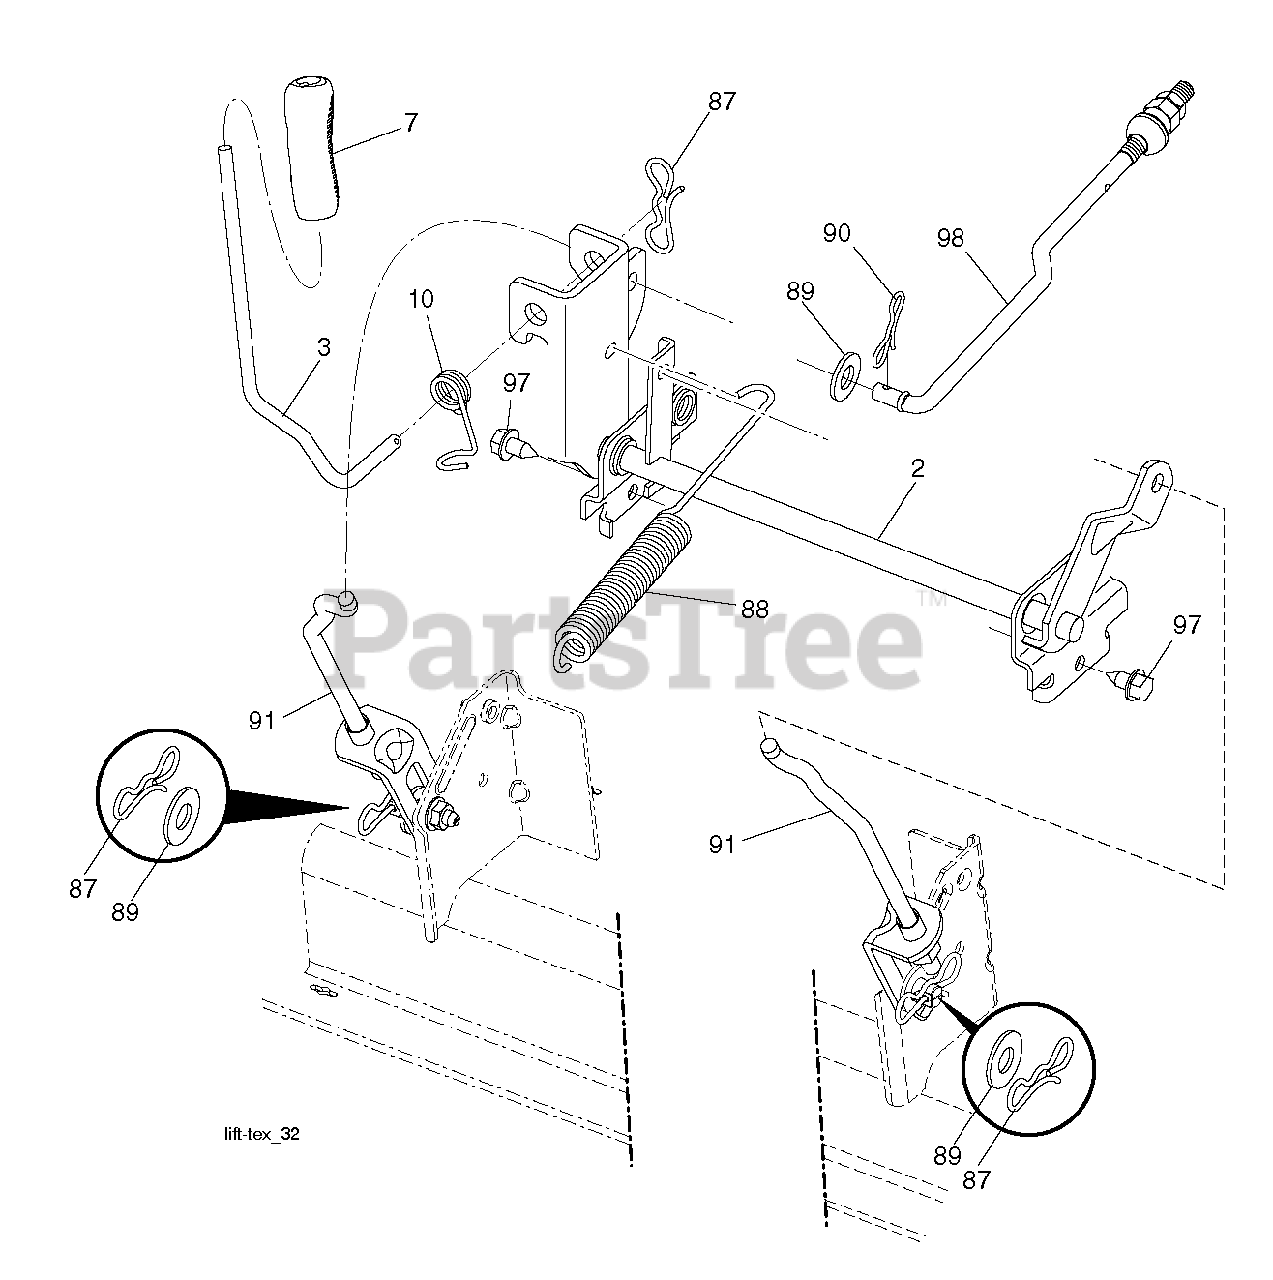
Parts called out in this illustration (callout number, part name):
2	SHAFT.ASM.CROSS.LIFT
3	LEVER.LIFT.HANDLE.LT
7	GRIP.HANDLE.LIFT.PVC.BLACK
10	SPRING.TORSION.LIFT.HANDLE
87	PIN.COTTER.7/16.BOW TI.
88	SPRING.LIFT.ASSIST
89	WASHER.CLEAR.ZINC
90	PIN.COTTER.5/16.BOW TI
91	LINK.LIFT.ASM.REAR.GT.
97	SCREW, 3/8-16X3/4
98	LINK.FRONT.MOWER.SUSP.ASM.BLK
